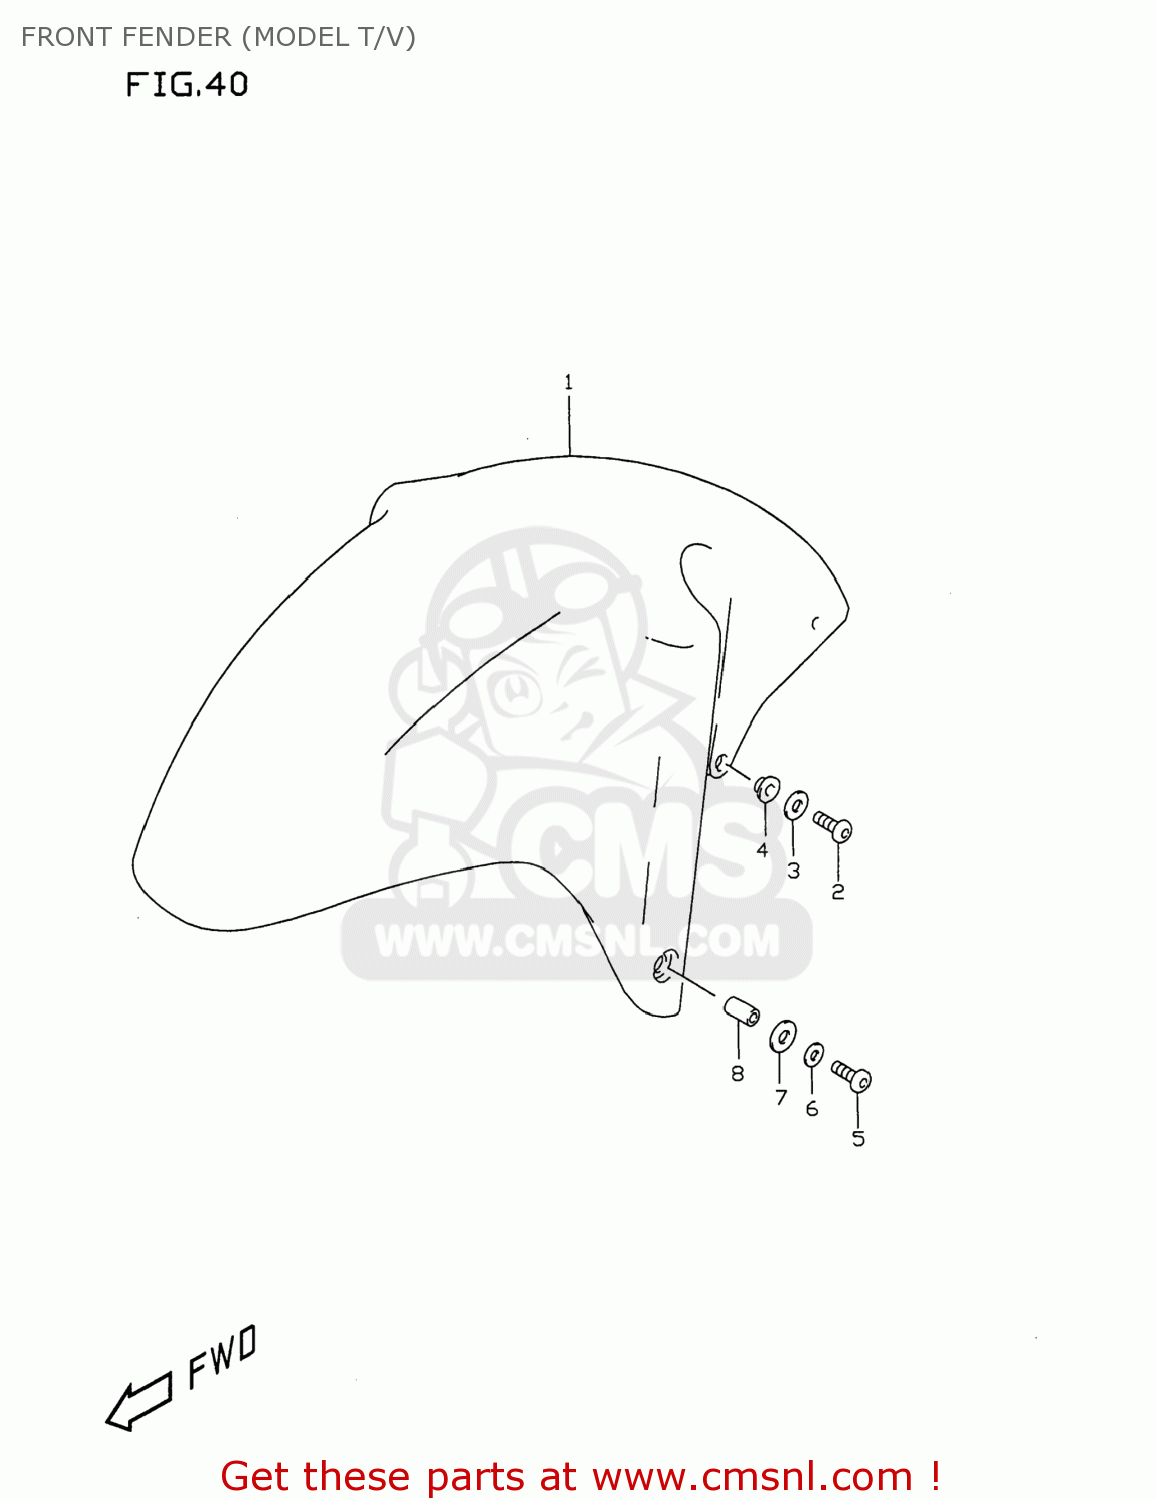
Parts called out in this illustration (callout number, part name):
1	FENDER COMP,FRONT
2	SCREW(6X16)
3	WASHER(6.5X16X1.2)
4	WASHER(6.3X16X1.5)
5	SCREW(6X16)
6	WASHER(6.5X16X1.2)
7	WASHER,FR FENDER FR NO.2
8	SPACER(6.5X9X6.7)
